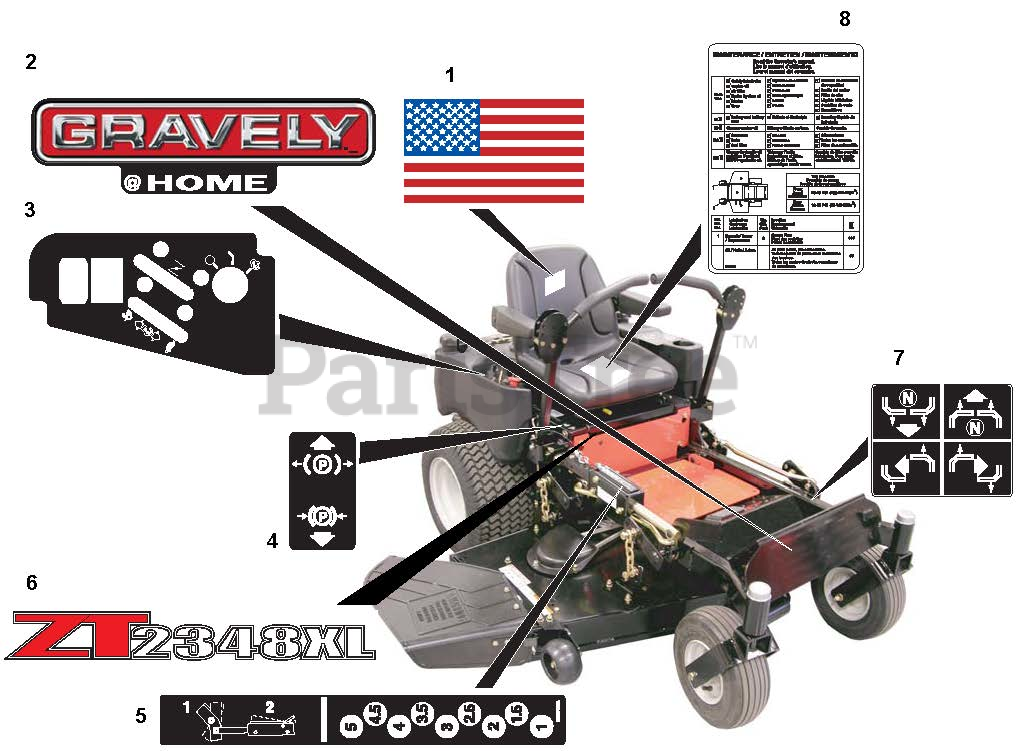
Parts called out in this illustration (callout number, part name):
1	Decal, American Flag
2	Decal, Gravely @ Home
3	Decal, Control Panel
4	Decal, Parking Brake Lever
5	Decal, Height of Cut
6	Decal, ZT 2348XL
6	Decal, ZT 2044XL
7	Decal, Instructional Steering
8	Decal, Service Instructions
